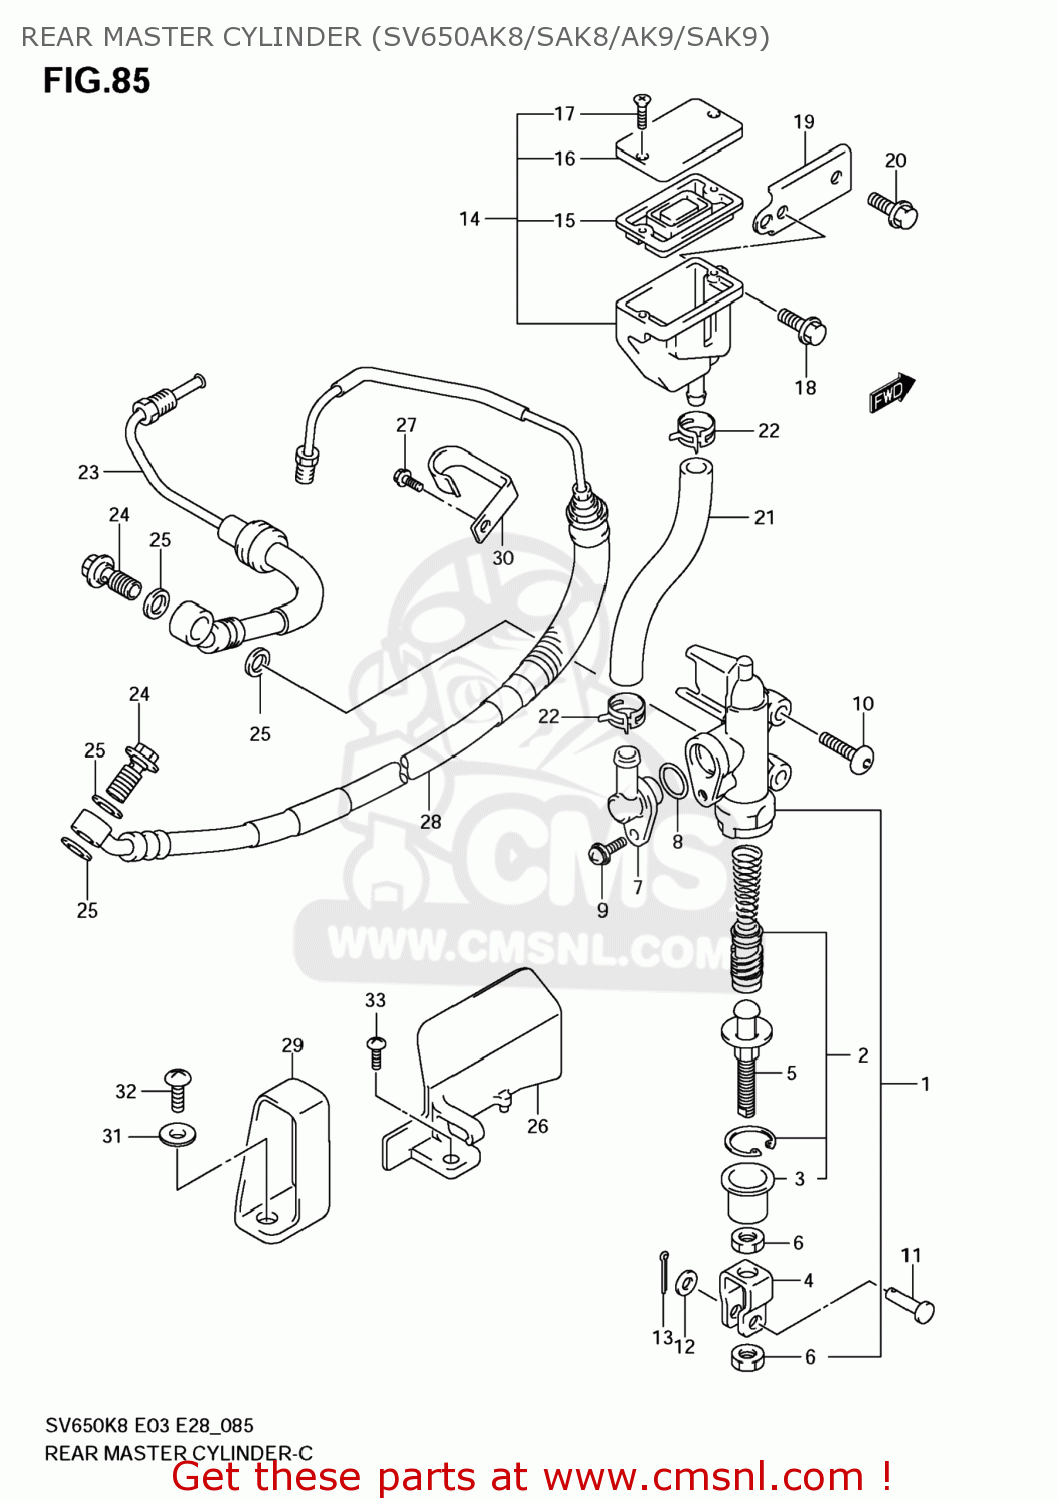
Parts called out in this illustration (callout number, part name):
1	CYLINDER ASSY,RR MASTER
2	PISTON/CUP SET
3	BOOT
4	YOKE
5	ROD,PUSH
6	NUT
7	CONNECTOR
8	O RING
9	SCREW
10	SCREW(6X20)
11	PIN(6X18.2)
12	WASHER
13	PIN
14	TANK ASSY,RR RESERVOIR
15	DIAPHRAGM
16	CAP
17	SCREW
18	BOLT(6X12)
19	BRACKET,RR RESERVOIR TANK
20	BOLT
21	HOSE,RR RESERVOIR TANK
22	CLIP
23	HOSE ASSY,RR BRAKE NO.1
24	BOLT UNION
25	WASHER(10X15X1.5)
26	GUIDE,RR BRAKE HOSE FR
27	BOLT
28	HOSE ASSY,RR BRAKE NO.2
29	GUIDE,RR BRAKE HOSE
30	CLAMP,RR BRAKE HOSE NO.2
31	WASHER
32	SCREW
33	SCREW
